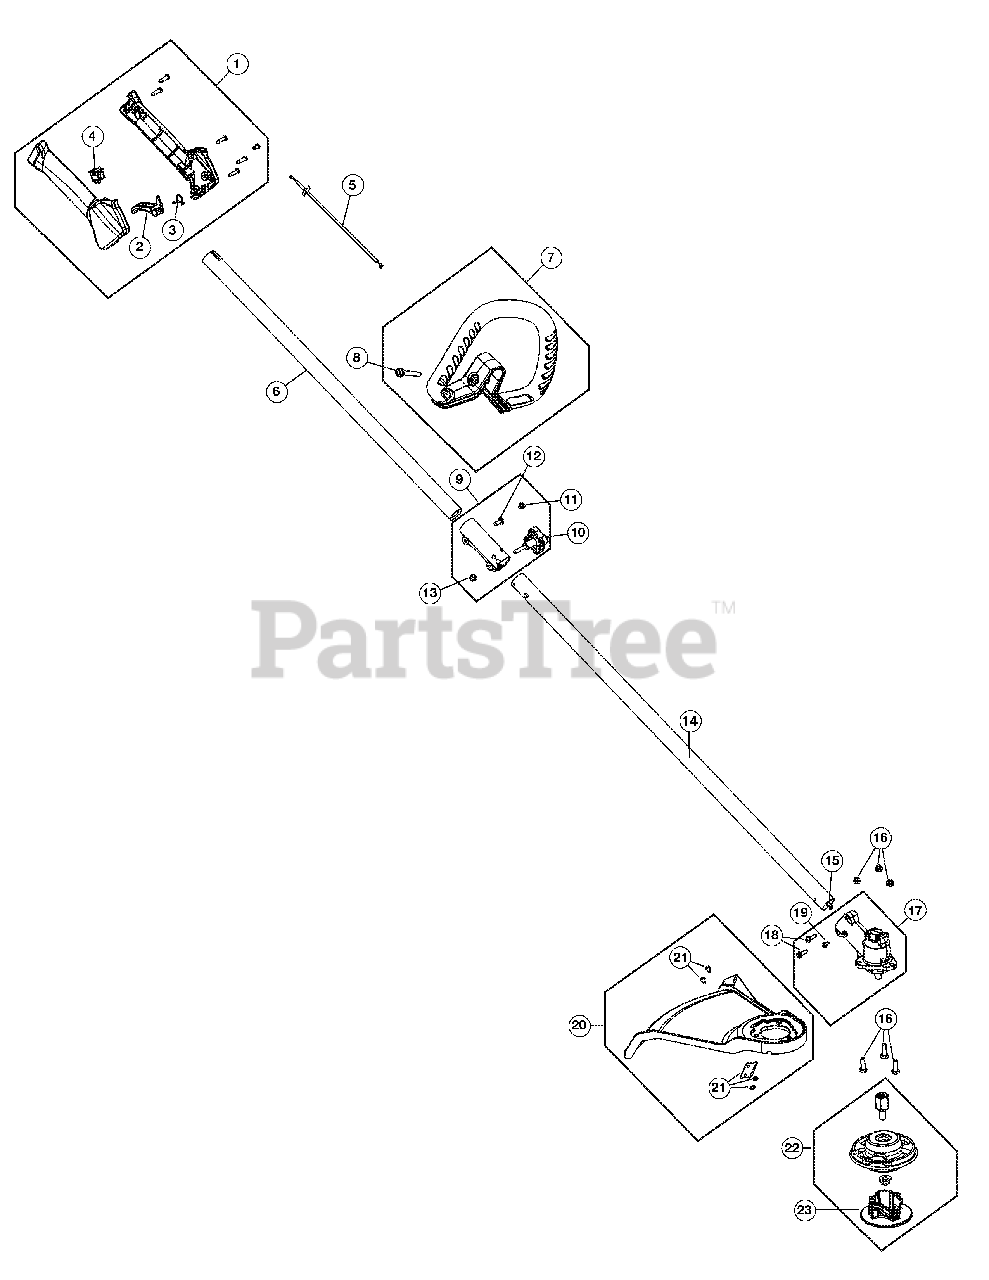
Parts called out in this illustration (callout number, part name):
1	Throttle Housing Assembly (Incl. Ref No. 2-4)
2	Throttle Trigger
3	Throttle Trigger Spring
4	Switch Assembly
5	Throttle Cable Assembly
6	Upper Drive Shaft Assembly
7	D-Handle Assembly (Incl. Ref No. 8-10)
9	Split Boom Coupler (Incl. Ref No. 10-13)
10	Adjustment Knob (Incl. Ref No. 15)
11	Coupler Anti-Rotation Screw
12	Coupler Bolt
13	Adjustment Knob Nut
14	Lower Drive Shaft Housing
15	Lower Flexible Drive Shaft
16	Shield Mount Screw Assembly
17	Gearbox Assembly (Incl. Ref No. 18 & 19)
18	Gearbox Screw
19	Gearbox Anti-Rotation Screw
20	Shield Assembly (Incl. Ref No. 21)
21	Blade Assembly
22	Cutting Head Assembly (Incl. Ref No. 23)
23	Cutting Head Cap
